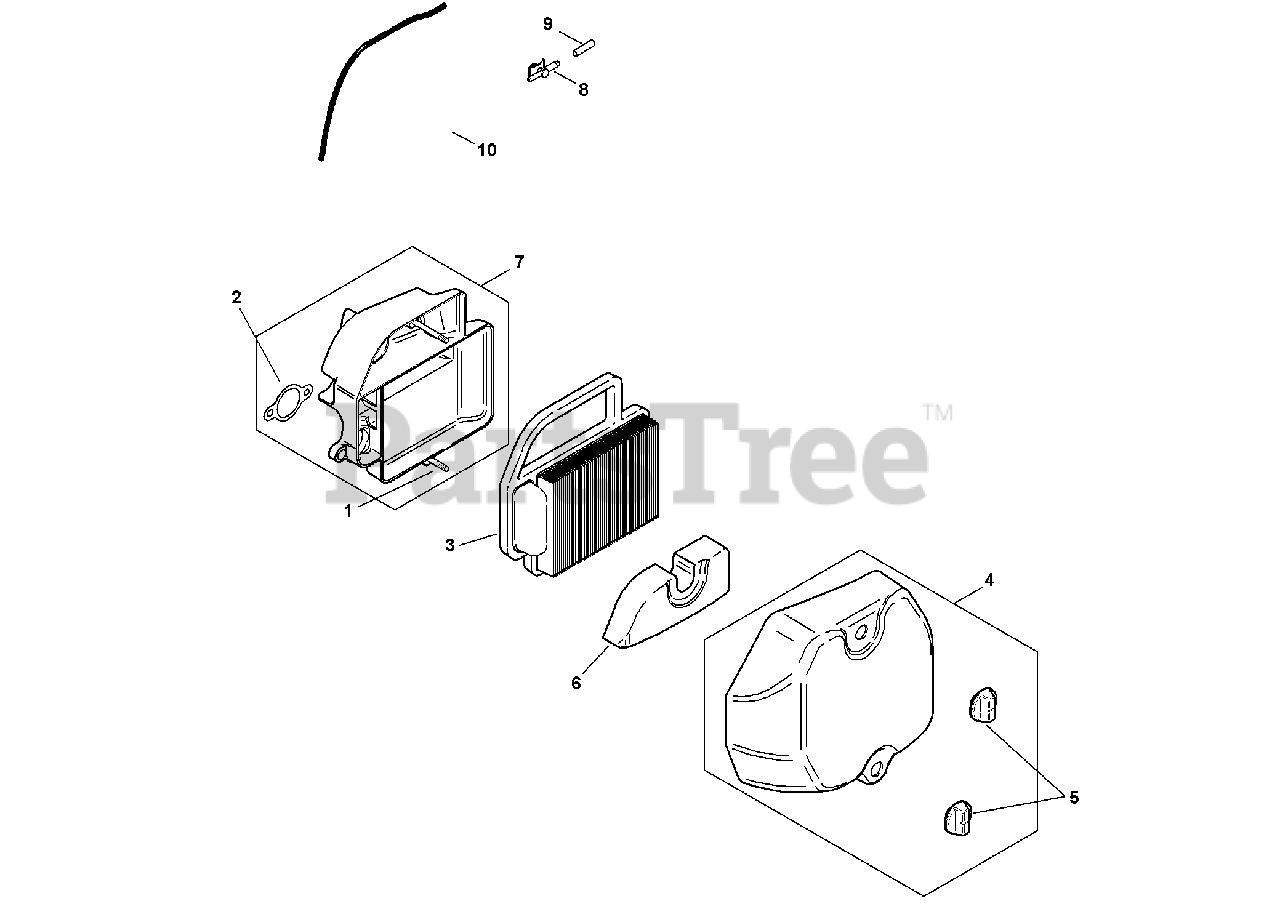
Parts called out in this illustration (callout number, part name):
1	Air Cleaner Base Stud
2	Air Cleaner Base Gasket
3	Air Cleaner Element
4	Air Cleaner Cover Kit
6	Pre-Cleaner Element (Dry)
7	Air Cleaner Base Kit
8	Evaporative Connector
10	Hose, Evaporative, 20"
